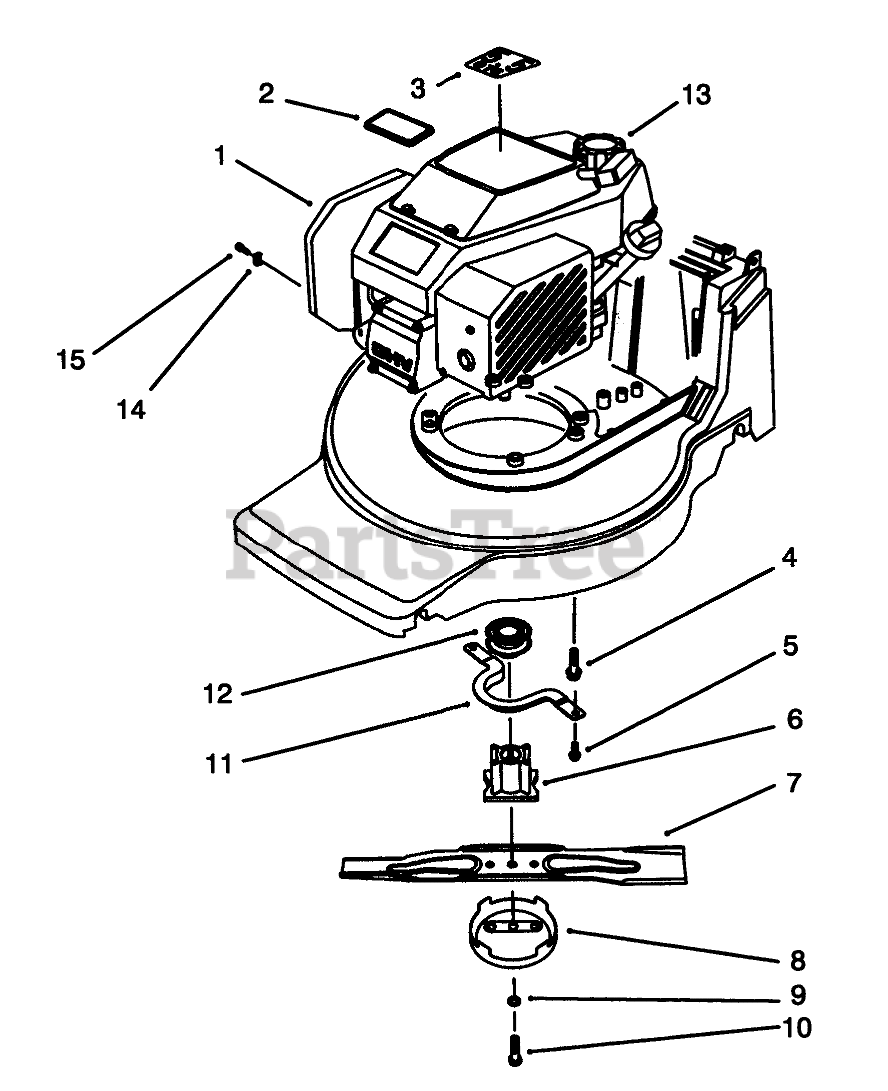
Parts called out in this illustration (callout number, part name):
1	ENG ASM-GTS 150 NC
2	PLATE-LOGO
3	DECAL - ENGINE
4	SCREW-HWH
5	SCREW-HWH
6	BLADE RETAINER - 25 MM
7	Blade-48cm
8	CUP-SCALP, ANTI
9	WASHER-LOCK
10	BOLT-BLADE
11	Guide-Belt
12	PULLEY-DRIVE, ZONE START
13	GAS CAP ASM
14	CLAMP-CASING
15	CLAMP SCREW F/W ENGINE
